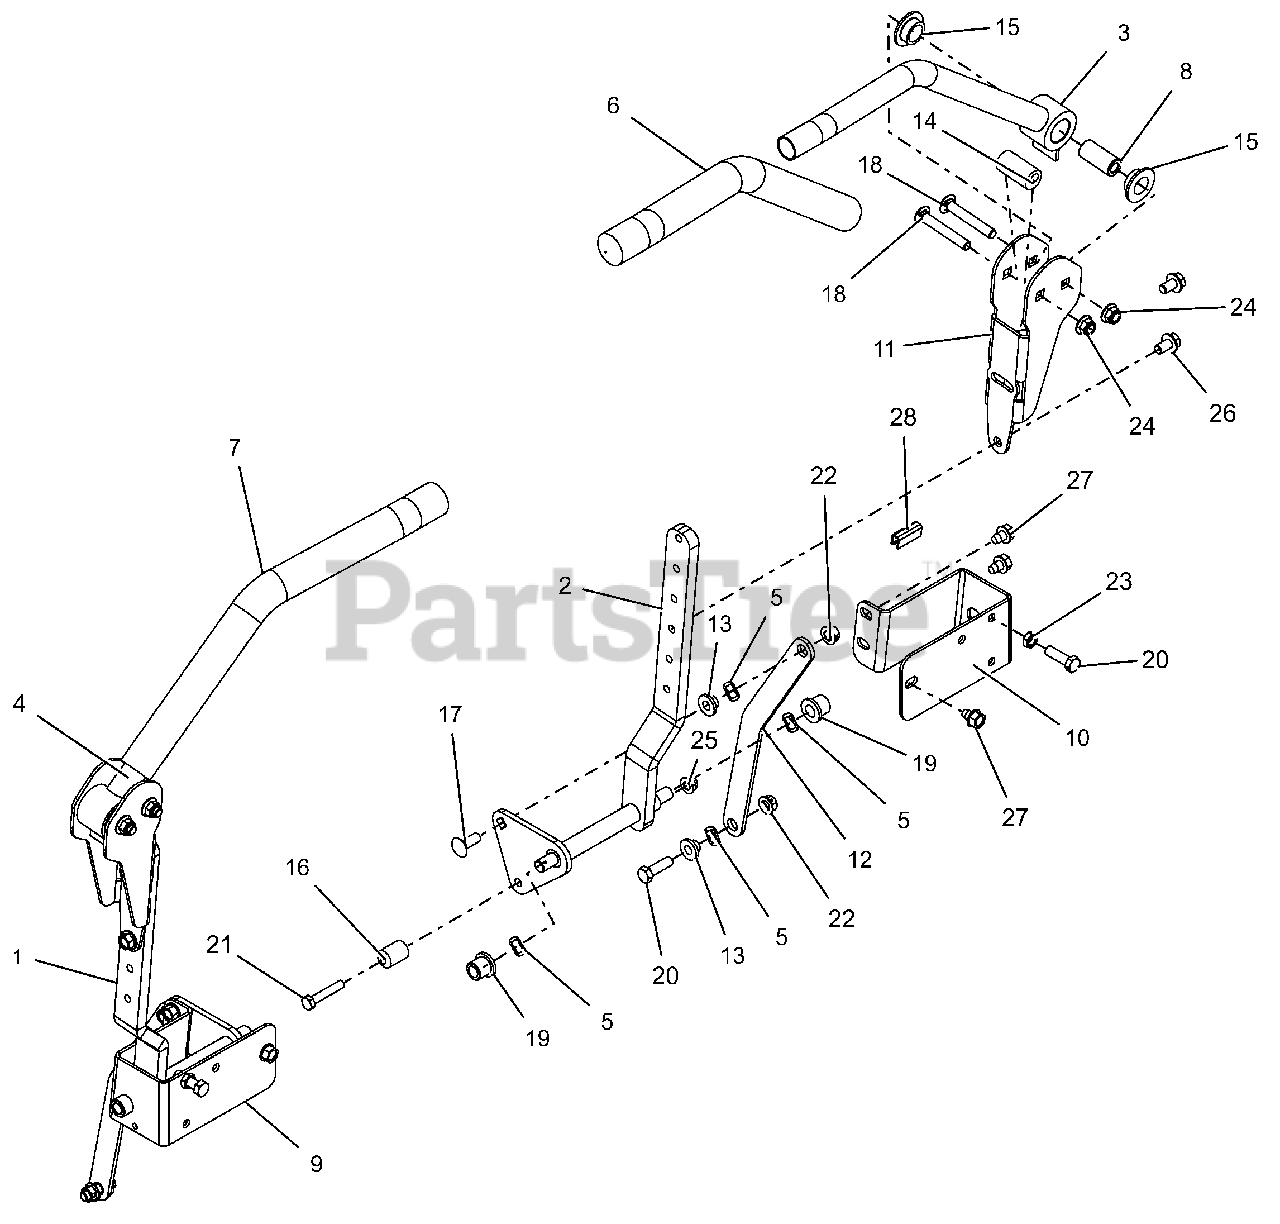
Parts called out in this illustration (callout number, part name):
1	WMT,PT/PT100RH LOWER CNTRL ARM
2	WMT,PT/PT100LH LOWER CNTRL ARM
3	WLDMT, CONTROL HANDLE- BLK
4	WLDMT, CONTROL HANDLE- BLK
5	WAVE WASHER .531X.781X.125FH
6	GRIP, HANDLEBAR
7	GRIP, HANDLEBAR
8	SPACER, STEERING ARM
9	RH PT/PT100 DRV CNTRL STOP-RED
10	LH PT/PT100 DRV CNTRL STOP-RED
11	ADJ UPPER CONTROL ARM BRKT-BLK
12	LINK, DRIVE CONTROL - BLACK
13	BSHG-FLG .385X.500X.875X.406
14	BSHG, ECCENTRIC.406X.875X1.625
15	BSHG-FLG .762X1.48X.44 NYL
16	ECCENTRIC
17	@BLT-RDHDSQNK .38-16X1.00 G5YZ
18	BLT-RDHDSQSHK, 38-16X2.50 G5YZ
19	BHSG-FLG .500X.750X.750X.125
20	@BLT-HEX .38-16X1.25 GR5 YWZC
21	@BLT-HEX .31-18X1.75 GR5 YWZC
22	NUT-LK-CTR-FLG .38-16 YWZC
23	NUT-HEX-JAM .375-16 YWZC
24	@NUT-LK-NYL-FLG .38-16 YWZC
25	@NUT-LK-NYL-FLG .31-18 YWZC
26	BLT, SCRHFWH .375-16X.625 YWZC
27	@SCR-TAP .38-16X.50 HWH TR YWZ
28	STRIP, COWL
